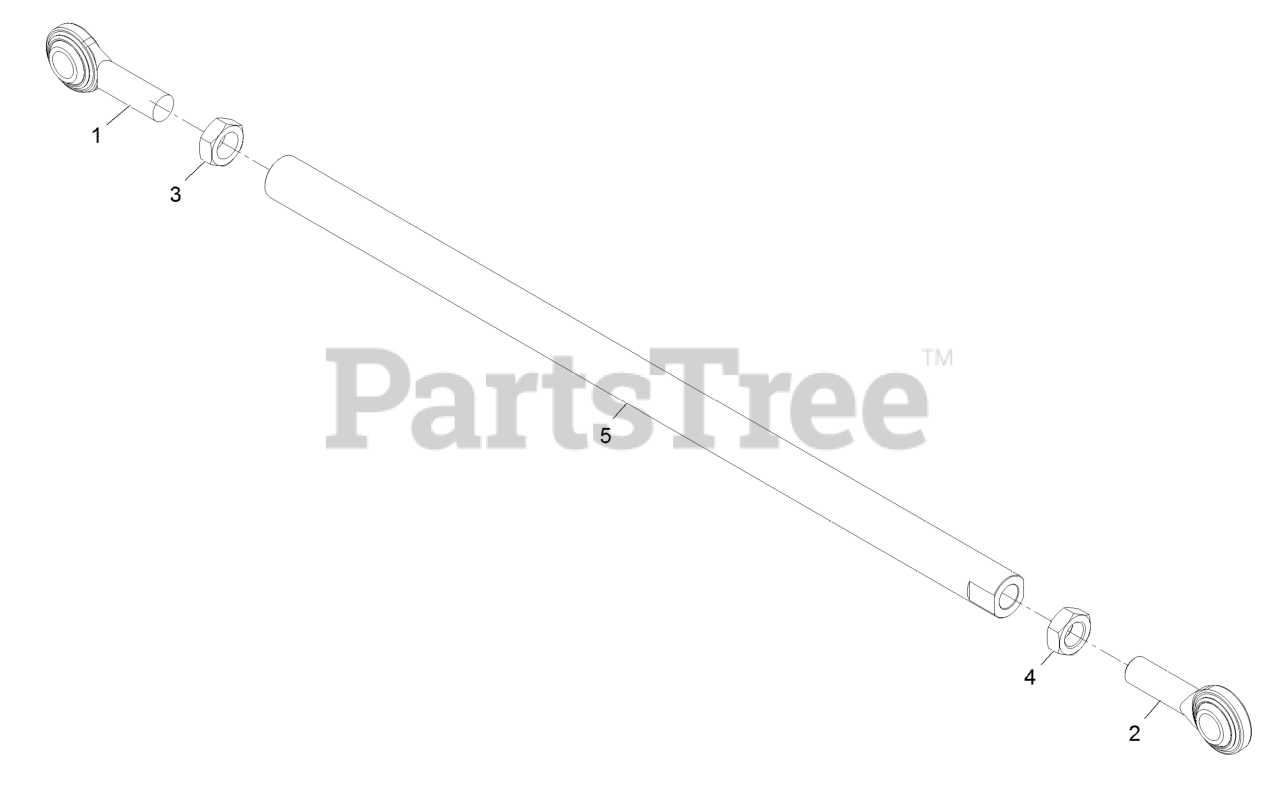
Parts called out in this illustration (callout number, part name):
1	BALLJOINT-SPHERICAL
2	BALLJOINT-SPHERICAL
3	NUT-JAM
4	NUT-JAM
5	LINK-HEIGHT OF CUT
